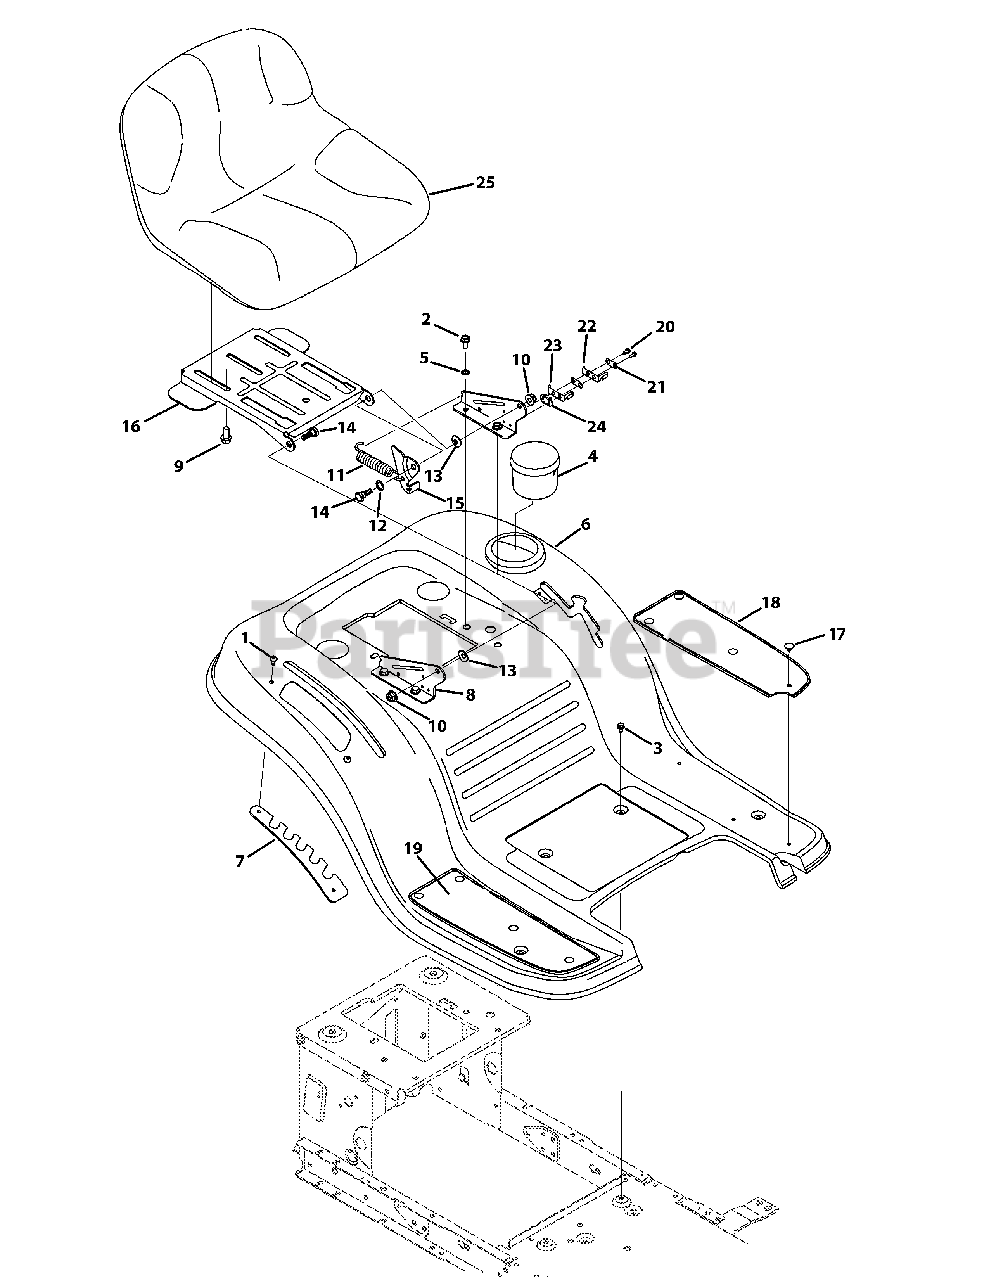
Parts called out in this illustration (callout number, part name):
1	Screw, 1/4-20 x .500
2	Screw, 5/16-18 x .750
3	Screw Pan Torx Head, 1/4-20 x .500
4	Cup Holder
5	Loack Washer, 5/16
6	Fender
7	Lift Adjuster Bracket
8	Seat Mount Bracket
9	Hex Flange, 3/8-16 x .875
10	Flangelock Nut, 5/16-18
11	Extension Spring
12	Flat Washer, .510x .750 x .033
13	Bell Washer, .340 x .872 x .060
14	Shoulder Screw, 5/16-18 x .437 x .268
15	Lift Seat Bracket
16	Pivot Seat Manual Adjust Bracket
17	Ratchet Clip, .250 x .500
18	Foot Pad, LH
19	Foot Pad, RH
20	Screw, 8-18 x .500
21	Insulator Plate
22	Outer Seat SPring
23	Inner Seat Spring
24	Insulator Boss Plate
25	Medium Back Seat
